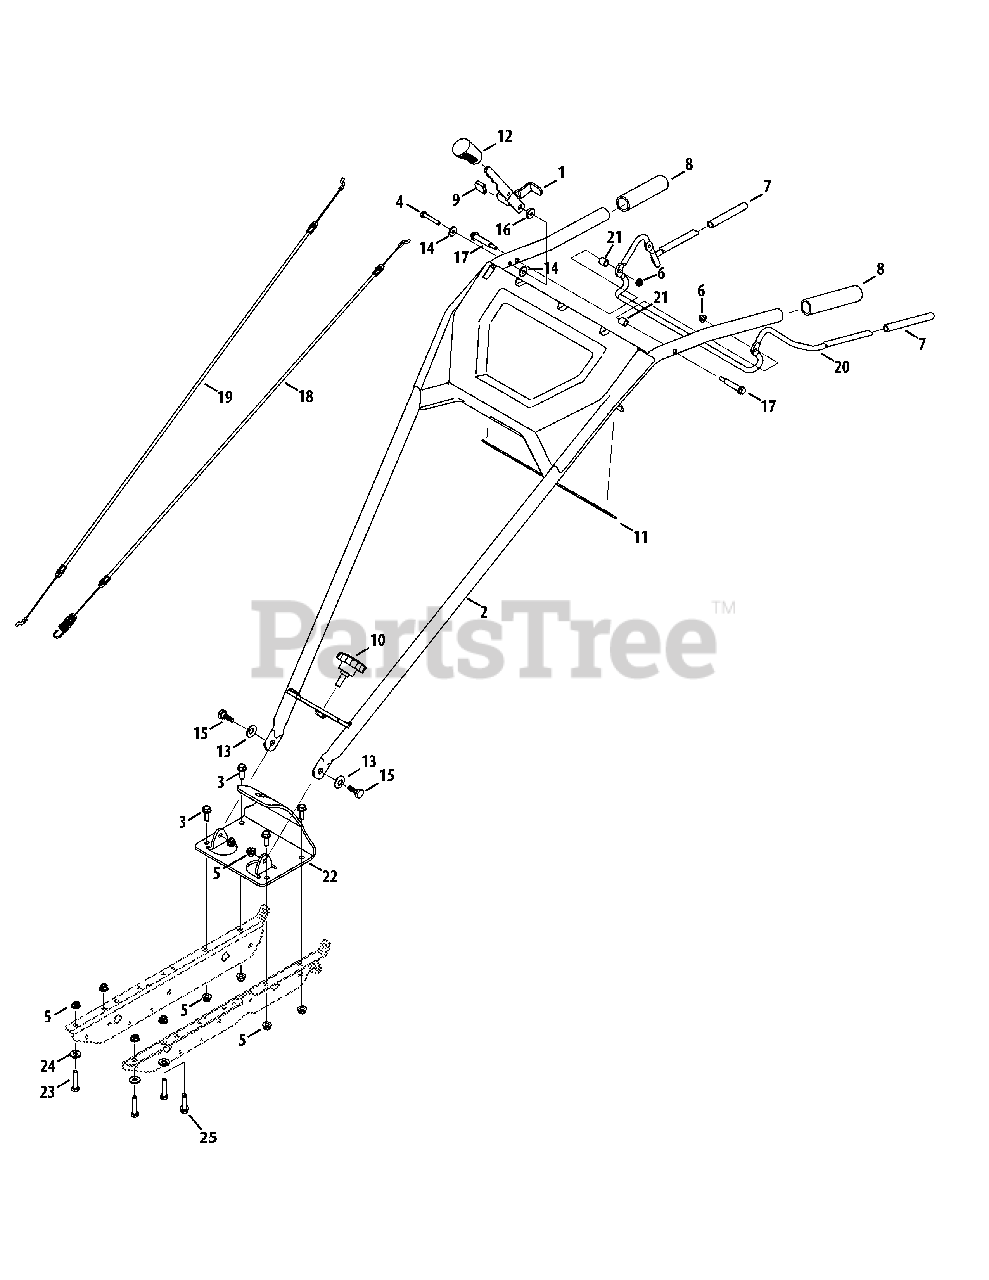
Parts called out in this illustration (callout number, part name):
1	Reverse Handle Assembly
3	Hex Head Washer, 5/16-18 x .875
4	Hex Head Screw, 1/4-20 x 1.62
5	Flangelock Nut, 5/16-18
6	Flangelock Nut, 1/4-20
7	Clutch Grip
9	Reverse Handle Grip
10	Star Knob, 3/8-16
11	Foam Tape, 1.25 x 13.53 x .10
12	Reverse Handle Grip
13	Bell Washer, .45 x 1.00 x .062
14	Washer, Flat, .250 x .750 x .119
15	Shoulder Screw, .437 x .268 x 5/16-18
16	Spacer, .375 x .165
17	Shoulder Screw, 1/4-20 .375 x 1.62
18	Forward Cable
19	Reverse Cable
21	Spacer, .383 x .500 x .535
22	Height Adjustment Mounting Plate
23	Hex Head Screw, 5/16-18 x 1.50
24	Washer, .396 x 1.140 x .095
25	Screw, 3/8-16 x 1.250 (B&S)
